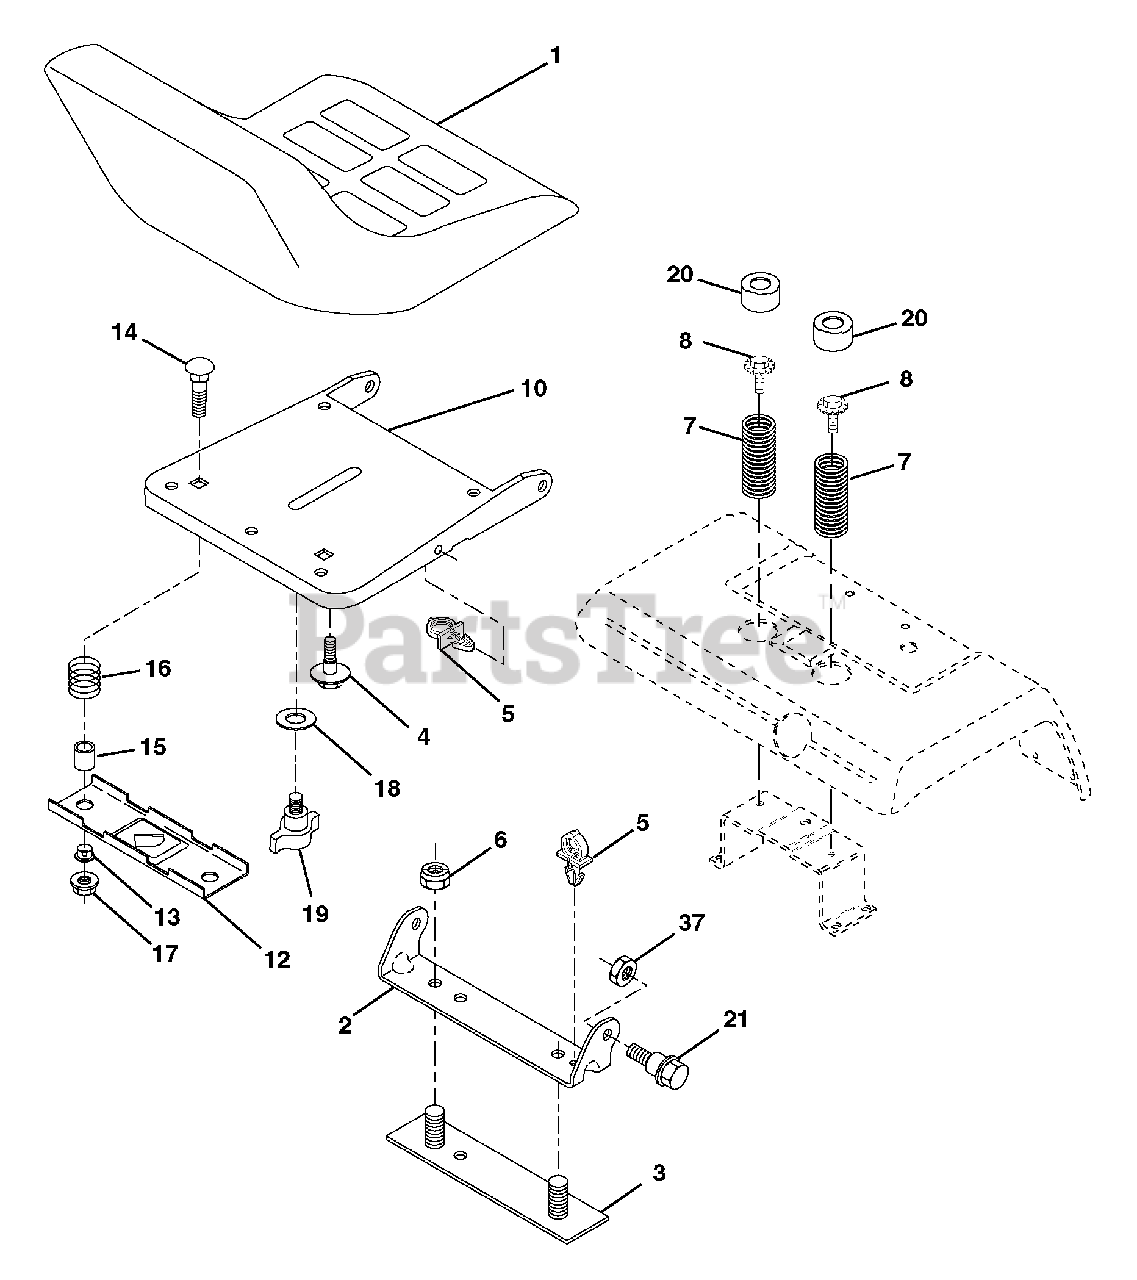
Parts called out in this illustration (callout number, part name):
1	Seat
2	Bracket, Pivot Seat
3	Strap Asm Fender
4	Bolt Shoulder 5/16-18 x .62
5	Clip, Push In Hinged
6	Nut, Crownlock 3/8-16
7	Spring, Seat Cprsn
8	Bolt 5/16-18 Unc x 3/4
10	Pan, Seat
12	Bracket, Mounting Switch
13	Bushing, Snap
14	Bolt, Carriage 1/4-20 x 1-1/2
15	Spacer, Split
16	Spring, Cprsn
17	Nut, Lock 1/4 Lge Flg Gr. 5
18	Washer 17/32 x 1-3/16 x 12 Ga.
20	Cap, Spring Seat
21	Bolt, Shoulder 5/16-18
22	Nut Crownlock 5/16-18
37	Nut, Crownlock 5/16-18
